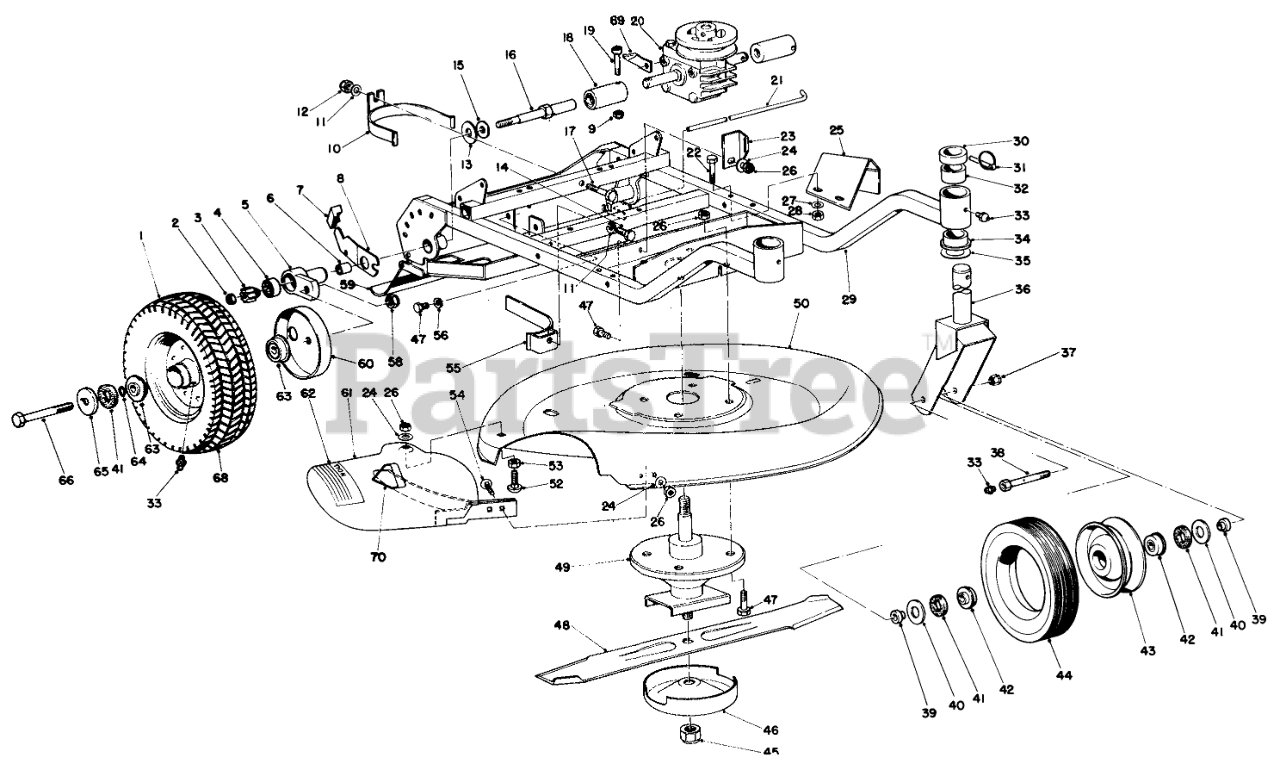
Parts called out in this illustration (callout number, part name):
1	Rear Wheel Assembly (Incl. Ref. #63)
2	NUT-HJ
3	Pinion Kit
4	.375 RPP BALL BEARING
5	Pivot Arm Assembly, Right (Incl. Ref. #4 & 6)
6	BUSHING
8	RH SPRING ARM ASM
9	NUT-LOCK, NI
10	Belt Retainer W.A.
11	WASHER-LOCK/SP
12	NUT-LOCK, NI
13	Washer
14	SCREW-HH
15	Washer
16	DRIVE SPINDLE
17	SCREW-HH
18	CLUTCH ASM
19	DRIVE SCREW
20	Transmission Assembly
21	SHIELD ROD
22	SCREW-HH
23	Belt Retainer
24	WASHER-PLAIN
25	Step Plate
26	Nut
27	WASHER-FLAT
28	NUT-LOCK
29	Frame (Incl. Ref #32 & 34)
30	HT OF CUT SPACER
31	PIN-LYNCH
32	7/8 ID X 1.128 X 7/8 LG BSHG
33	FITTING-GREASE
34	FLANGE BUSHING
35	WASHER
36	CASTOR FORK WA RO
37	NUT-HEX
38	AXLE BOLT
39	CASTOR SPACER
40	WASHER-FLAT
41	Washer
42	BEARING-BALL
43	Wheel (Incl. Ref. #42 & 44)
44	1.75-8 SEMIPNEU TIRE
46	Cup
47	SCREW-HH
48	Blade
49	Mower Spindle
50	25" DECK R
52	SCREW-CARR
53	PAL NUT
54	BOLT-CARR
55	Belt Retainer
56	Lockwasher
58	NUT-LOCK, NI
59	REAR SAFETY SHIELD
60	Wheel Cover
61	DefIector
62	Decal
63	BEARING
64	O-RING
65	SLINGER
66	SCREW-HH
68	3.50X10 SEMIPNEU TIRE
69	Retainer
70	DECAL-DANGER
